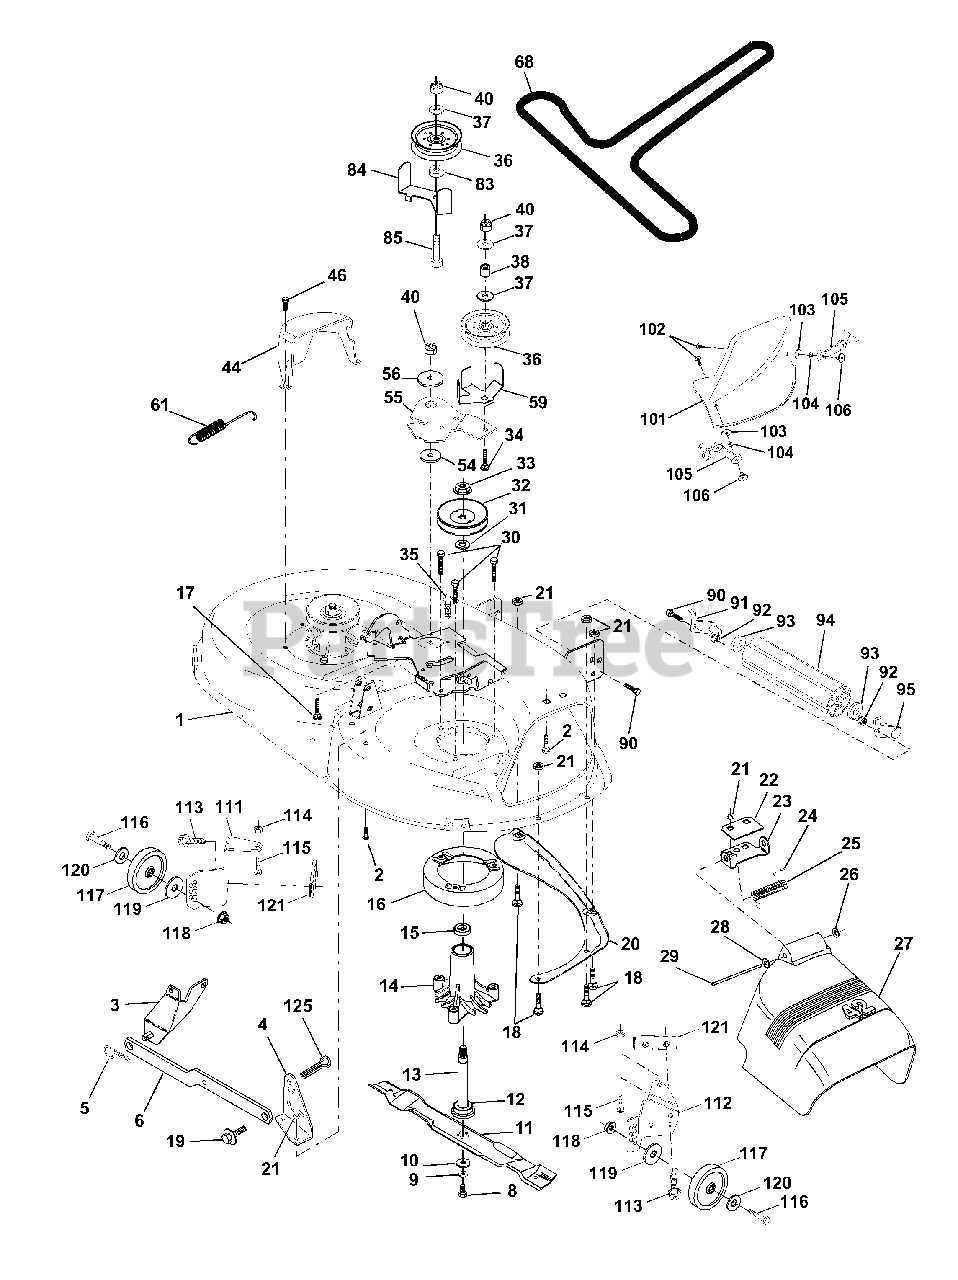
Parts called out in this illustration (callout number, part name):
1	Deck Asm MWR 42" weldment
2	Bolt Rdhd Sqnk 5/16-18unc X3/4
3	Bracket Asm Fr Sway Bar 38/42
4	Bracket Asm Deck 42" sway Bar
5	Retainer Spring
6	Arm Suspension Rear
8	Bolt 3/8-24x1 25 Gr8 Patched
9	Washer Lock Hvy 3/8 Unplated
10	Washer Hard Blade Mower Vented
11	Blade Mower Mulching 42"
12	Bearing Ball #6204 (Mandrel)
13	Shaft Asm W/lower Bearing
14	Housing Mandrel Vented(machd)
15	Bearing Ball Mandrel
16	Stripper Mower Vented
17	Bolt Carriage 3/8-16 X 2-1/4
18	Bolt Carr 5/16-18 X 5/8
19	Bolt Shoulder
20	Baffle Vortex 42
21	Nut Crown Lock 5/16-18
22	Stiffener Bracket 42" deck
23	Bracket Deflector Mower 42"
24	Cap Sleeve 80x 112 Blk Mower
25	Spring Torsion Deflector 2 52
26	Nut Push Phos & Oil
27	Shield Deflector Mower 42" Blk
28	Washer 11/32 X 5/8 X 16 Ga
29	Rod Hinge 42" 6 75 Wlg
30	Screw Thdrol Hex Hd Zinc Mwr.
31	Washer Spacer Mower Vented
32	Pulley Mandrel 42"
33	Nut 9/16top Lock Flng Cntr
34	Bolt Rdhd 3/8-16uncx2-3/4 Gr5
35	Fastner Christmas Tree
36	Pulley Idler Flat 3 060
37	Washer 13/32 X 13/16 X 16 Ga
38	Spacer Spring Stop Idler
40	Nut Crownlock 3/8-16 Unc
44	Guard Mandrel LH Black
46	Screw Thdrol 1/4-20x5/8
54	Washer Hardened
55	Arm Idler 42" mower LT/YT
56	Spacer Retainer Pm Mower
59	Guard, Belt
61	Spring Ext. Elect
68	V-Belt Mower
83	Washer Sintered
84	Keeper Belt Idler Fixed
85	Bolt Carriage 3/8-16 x 2-1/2 Gr. 5
90	Bolt Fin Hex 3/8-16unc X 1
91	Bracket Asm Noseroller LH
92	Nut Lock 3/8-16 Unc
93	Washer 17/32 X 7/8 X 16 Ga
94	Roller Nose 38 & 42
95	Bracket Asm Noseroller RH
101	Cover Mulching 42" Black
102	Screw
103	Washer #10
104	Washer Lock #10
105	Latch Asm. Bagger
106	Nut Weld
111	Bracket Wheel Gauge Lh 42" Deck
112	Bracket Wheel Gauge Rh 42" Deck
113	Screw Thdrol 5/16-18 x 3/4
114	Nut Keps 5/16-18 UNC
115	Bolt Carriage 5/16-Unc x 1/2
116	Bolt Shld "A" 2.41 "B" 1.66
117	Wheel Gauge blk. 4.93
118	Nut Centerlock 3/8-16 UNC
119	Washer 3/8 x 7/8 x 14 Ga.
120	Washer 17/32 x 15/16 x 12 Ga.
121	Bracket Extruded Gauge Wheel
125	Pin Cotter 1/4 x 1 Plated
